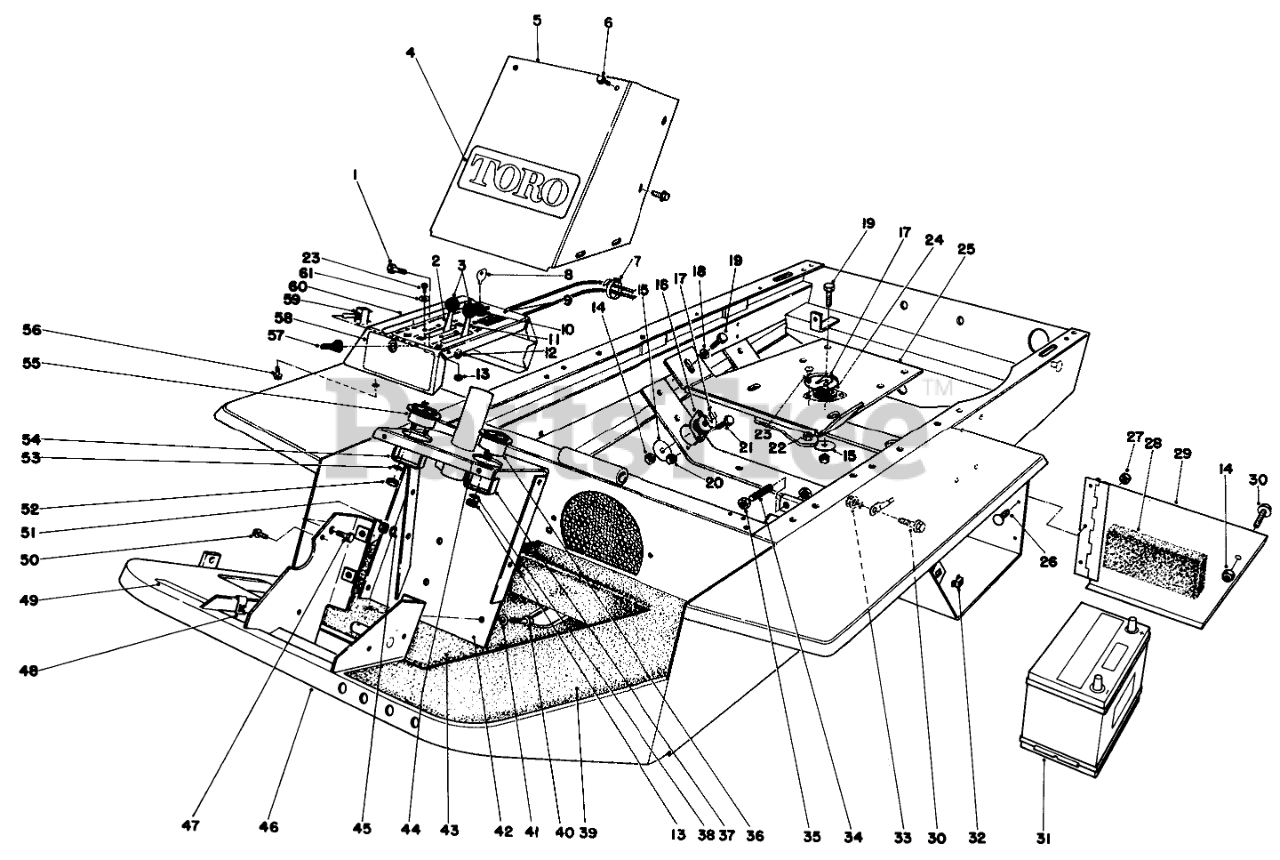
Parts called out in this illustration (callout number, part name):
1	SCREW-HH
2	CHOKE CONTROL
4	Decal
5	Tower Cover
6	SCREW-HHFTF
7	TIE-CABLE
8	Key
9	Decal-Instrument Panel
10	SWITCH
11	THROTTLE CONTROL
12	WASHER-FLAT
13	NUT-HEX
14	NUT-LOCK, NI
15	WASHER
16	ENGINE RUBBER MT
17	SHIM-AXLE
18	WASHER-FLAT
19	SCREW-HH
20	NUT-LOCK, NI
21	SCREW-HH
22	NUT-LOCK, NI
23	10-24 X 5/8 PAN HD MS
24	RUBBER MOUNT
25	Base-Engine
26	SCREW-HSBH
27	NUT-LOCK, NI
28	BATT BOX FOAM
29	Battery Cover
30	SCREW-HHF
31	Battery Assy.
32	RETAINER NUT
33	NUT-HHF, WHIZ
34	STOP PIN PP
35	NUT-JAM
36	HOUR METER
37	BRACKET F/W
38	WASHER-LOCK, INT
39	NON SKID (TUNNEL)
40	SCREW-HH
41	WASHER-LOCK
42	Steering Post
43	NON-SKID-FLOOR
44	INSTRUCTION DECAL
45	WASHER-LOCK
46	FRAME WA
47	SCREW-HH
48	SPEED NUT
49	DECAL-PEDAL, TRACTION
50	SCREW-HWH
51	NUT-HEX
52	NUT-HEX
53	WASHER-FLAT
54	MTG CLAMP F/W GUAGE
55	AMMETER GAUGE ASSY
56	SCREW-THD FRM,HWH
57	BOOT-SWITCH
58	BY-PASS DECAL
59	Switch-Toggle (Incl. Ref. #57)
60	Instrument Panel
61	WASHER-LOCK
